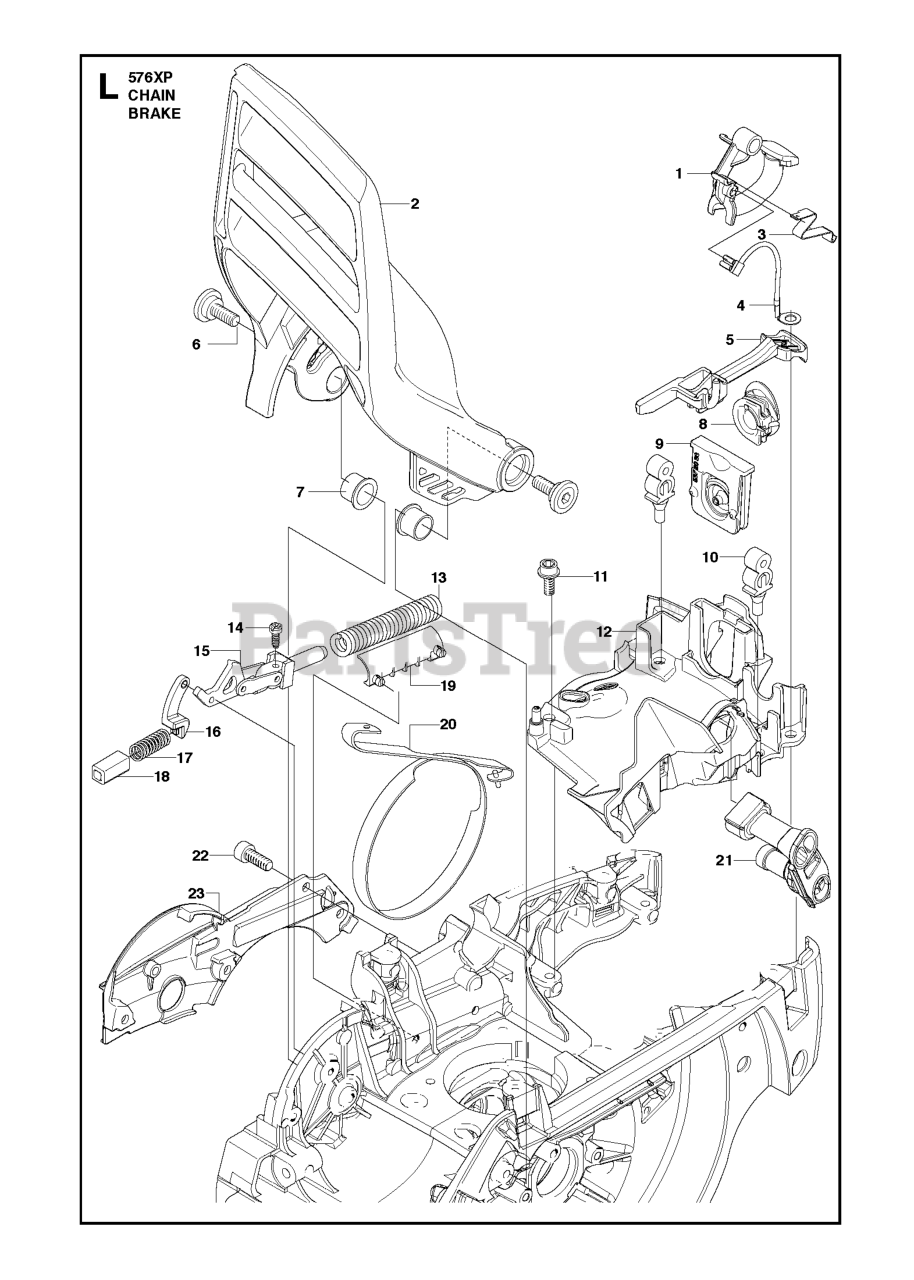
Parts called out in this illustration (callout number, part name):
2	CHAIN BRAKE
5	CHOKE CONTROL
10	SUPPORT
11	SCREW
13	BRAKE SPRING
15	KNEE JOINT
17	LOCK SPRING
20	BRAKE BAND
21	SLEEVE
